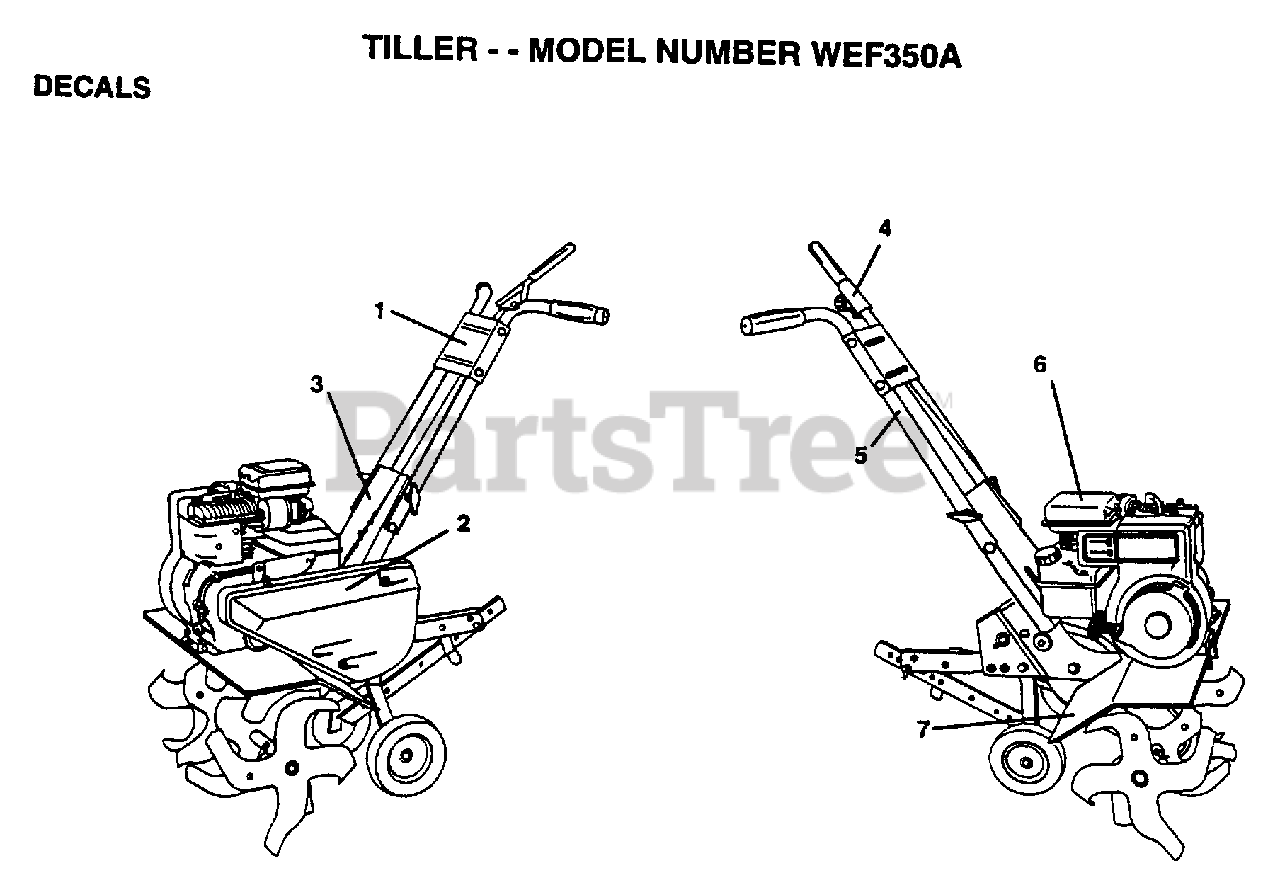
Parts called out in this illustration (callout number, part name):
2	DECAL.BELT.GUARD
3	DECAL.LOWER.PANEL
4	DECAL TI
5	DECAL TI
6	DECAL TI
